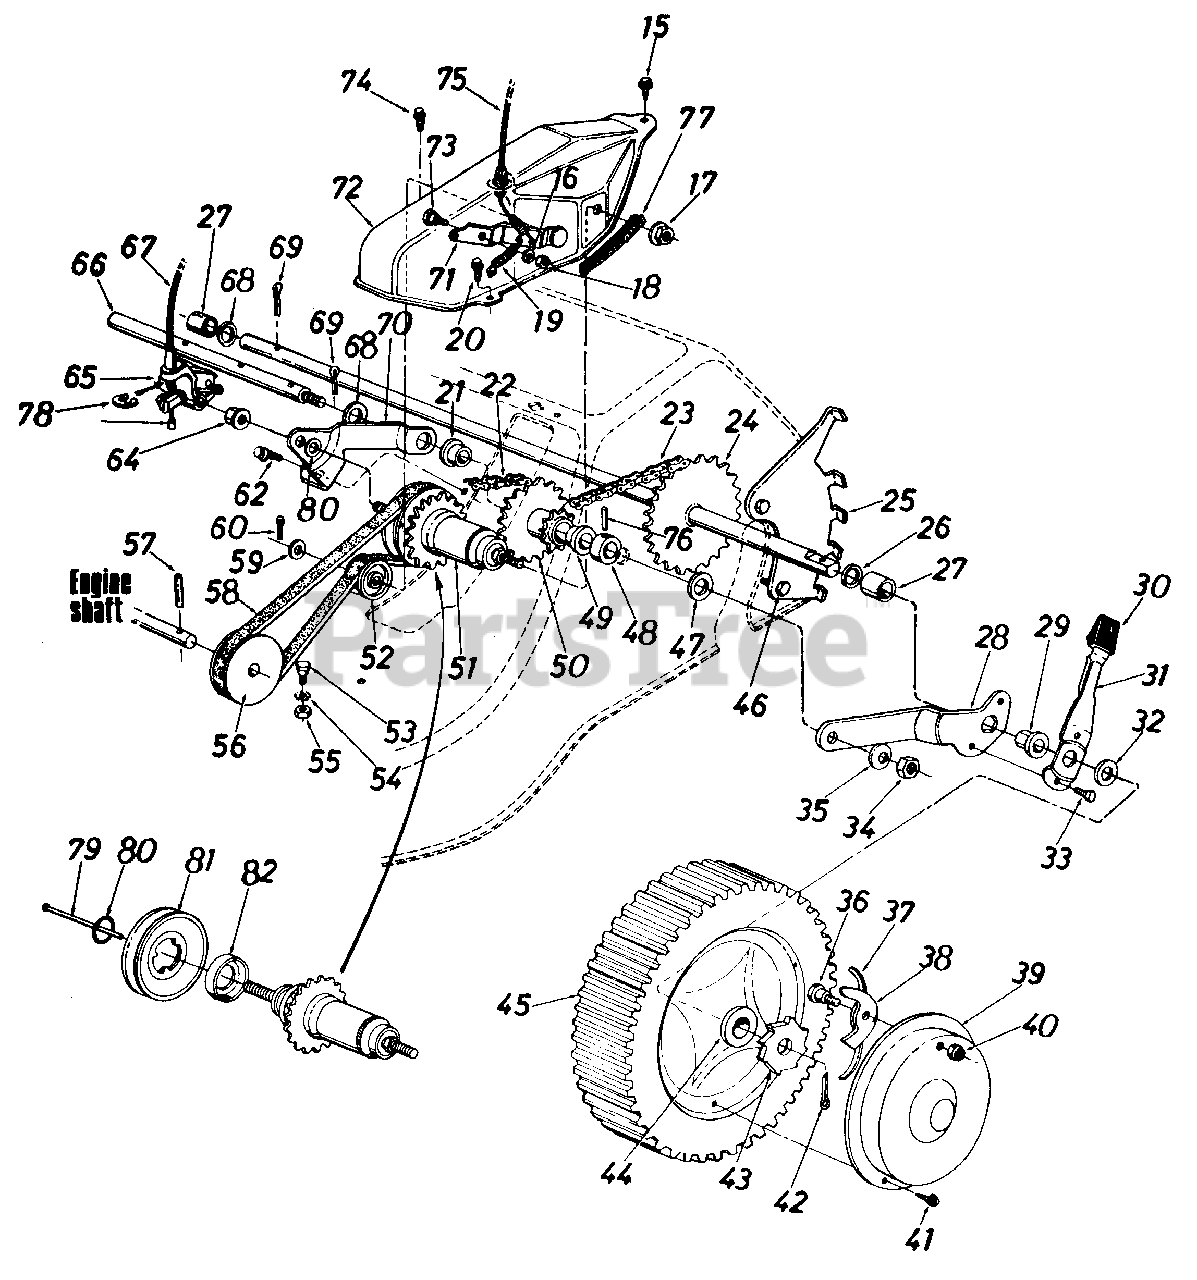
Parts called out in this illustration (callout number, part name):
15	Hex Drilling Scr. #10 x .50" Lg.
16	L-Wash. 1/4" I.D.*
17	Hex Nut 3/8-24 Thd.
18	Hex Nut 1/4-20 Thd.*
19	Extension Spring .33" O.D. x 1.12" Lg.
20	Hex Wash. S-Tap Scr. 1/4-20 x .50" Lg.
21	Flg. Brg. .506" I.D.-Plastic
22	#48 Chain 1/2" Pitch x 38 Links
23	#48 Chain 1/2" Pitch x 32 Links
24	Rear Shaft Ass'y. 20.75"
25	Index Plate Rear-L.H.
26	Fl-Wash. .510" I.D. x 1.0"
27	Spacer .740" I.D. x .83" O.D.
28	Pivot Brkt.-L.H.
29	Hex Flange Brg. .506" I .D.-Plastic
30	Spring Lever Knob
31	Spring Lever
32	Fl-Wash. .531" I.D. x .930"
33	Hex B-Tap Scr. 1/4 x .38"
34	Hex Jam Nut 3/8-16 Thd.
35	Bell-Wash. .400" I.D. x .88"
36	Shld. Bolt .342" Dia. x .268
37	Spring-Nylon
38	Pawl
39	Hub Cap
40	Hex Ins. L-Nut 1/4-20 Thd.
41	Pan Hd. Tap Scr. #12 x .50" Lg. *
42	Cotter Pin 1/8" Dia. x 1.0"*
43	Ratchet Wheel 1.62" O.D.
44	Fl-Ball Brg. 1/2" I.D.
45	Wheel Ass'y. Comp. 8 x 1.75
46	Hex L-Wash. Hd. AB-Tap Scr. 1/4 x.62" Lg.
47	Bell-Wash. .400" I.D. x 1.13" O.D.
48	Spacer .505" I.D. x .88" O.D.
49	Flg. Brg. .506" I D. Plastic
50	9 and 21 Tooth Sprocket Ass'y.
51	Shimano 3-Sp. Hub w/18 Tooth Sprocket
52	Fl-Idler Plastic 1.62" Dia.
53	Shld. Bolt .437" Dia. x .180
54	L-Wash. 5/16" I.D.
55	Hex Nut 5/16-18 Thd.
56	1/2" "V"-Engine Pulley .50" I.D. x 2.80" O.D.
57	Spring Pin Spir. 3116" Dia. x 1.50" Lg.
58	"V"-Belt 1/2" x 26.0" Lg.
59	Fl-Wash. .531" I.D. x .930"
60	Cotter Pin 1/8" Dia. x 1.0"
62	Hex Wash. Hd. Tap Scr. 5/16-18 x .75" Lg.
64	Hex Nut 3/8-24 Thd.
65	Shimano 3-Sp. Shift Bell Crank
66	Pulley Shaft 10" Lg.
67	Shimano 3-Sp. Solid Shift Gable
68	Fl-Wash. .531" I.D. x .930"
69	Cotter Pin 3132" Dia. x 1.0"
70	3-Sp. Hub Bracket
71	Idler Bracket Ass'y.
72	3-Sp. Belt Cover
73	Shld. Bolt .375"1 Dia. x .181
74	Hex TT-Tap Scr. 1/4-20 x .75" Lg.
75	S.P. Cable-53" Lg.-Blue
76	Spring Pin Spir. 3116" Dia. x 1.0" Lg.
77	Trim Strip
78	Snap Ring
79	Shifting Pin
80	Pulley Snap Ring
81	1/2" V-Pulley 1.375" I.D. x 3.25" O.D.
82	Shimano 3-Sp. Dust Cover
